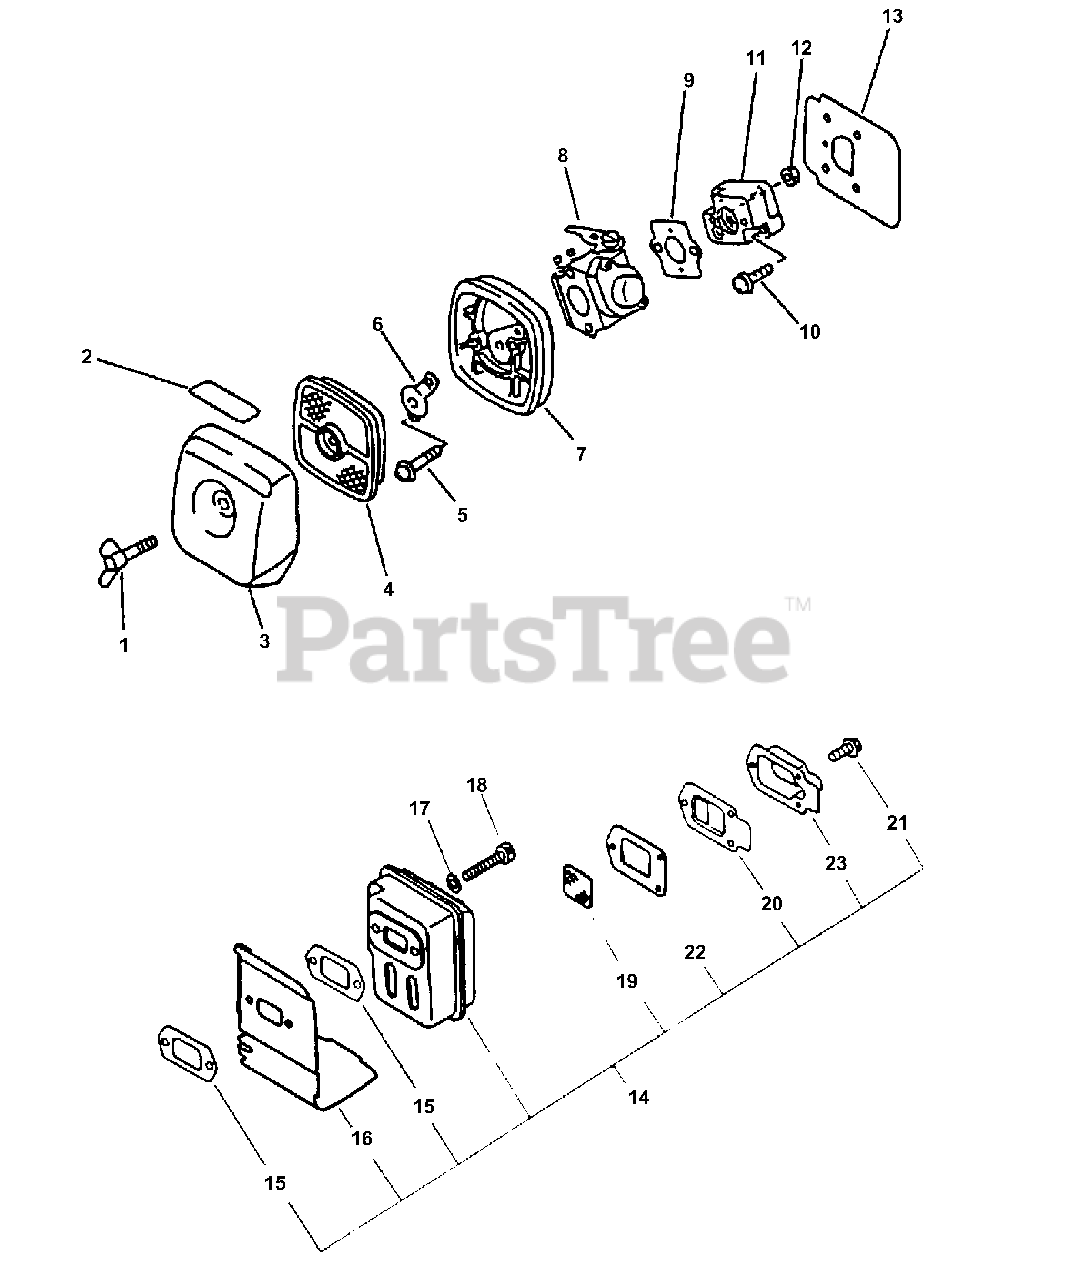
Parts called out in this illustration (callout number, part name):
1	BOLT, WING 5×20
2	LABEL, CHOKE
3	COVER, AIR FILTER - GRAY
4	FILTER, AIR - SINGLE LAYER
5	SCREW 5×65
6	PLATE, PREVENT
7	AIR FILTER CASE ASSY
8	CARBURETOR - C1U-K47
8	CARBURETOR - C1U-K52
9	GASKET, INTAKE
10	SCREW 5×20
11	INSULATOR, INTAKE
12	NUT M5
13	HEAT SHIELD, INTAKE
14	MUFFLER ASSY
15	GASKET, EXHAUST
16	COVER, EXHAUST
17	WASHER, FLAT 5.5×10×0.8
18	BOLT 5×55
19	SCREEN, SPARK ARRESTER
20	GUIDE, EXHAUST
21	SCREW 4×10
22	GASKET, EXHAUST
23	GUIDE, EXHAUST - INNER
